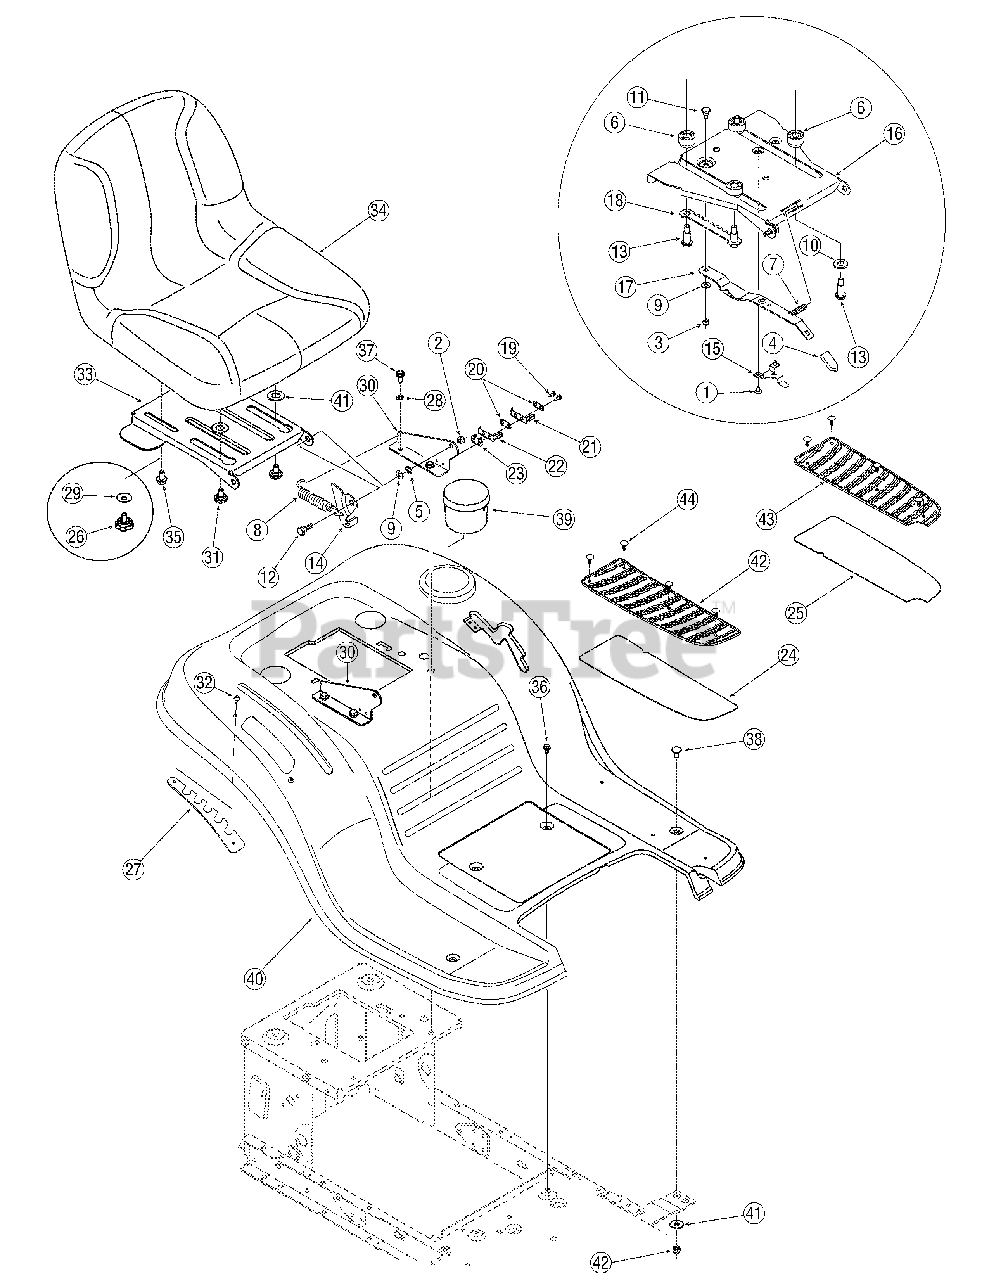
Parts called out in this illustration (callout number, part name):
1	Screw, #10-16, .375
2	Nut, Flange Lock, 5/16-18, GrF
3	Nut, Flange Lock, 1/4-20
4	Seat Adjuster Grip
5	Nut, Speed, .3125 Id
7	Compression Spring, .41 x 1.5
8	Spring, Exten., .84 Dia x 4.6 Lg.
9	Wash, Flat, .340 x .872 x .060
10	Wash, Flat, .531x 1.062 x.134
11	Screw, Shlder, .340 x .285,1/4-20
12	Scr., Shlder, .437 x .268, 5/16-18
13	Screw, Shlder, .50 x .925, 3/8-16
14	Lift Bracket, Seat
18	Seat Adjustment Selector
19	Screw, #8-18 x .50
20	Plate, Insulator
21	Spring Switch, Outer
22	Spring Switch, Inner
23	Plate, Insulator Boss
24	Foot Pad, Abrasive, RH
25	Foot Pad, Abrasive, LH
26	Knob, 3/8-16, .875
28	Lock Washer, 5/16
29	Washer, Flat, .406 x 1.00 x .030
31	Screw, Shlder, .625 x .175, 3/8-16
32	Screw, 1/4-20 x .500
34	Seat, Low, Black
34	Seat, Medium, Black
34	Seat, Low, Yellow
35	Screw, 3/8-16, .875
36	Screw, 1/4-20, 0.500
37	Screw, 5/16-18, 0.625
40	Flat Washer, .406 x .875 x .059
41	Flat Washer, .395 x .62 x .063
42	Foot Pad, Rubber RH
43	Foot Pad, Rubber LH
44	Ratchet Clip (For use w/ rubber foot pad)
